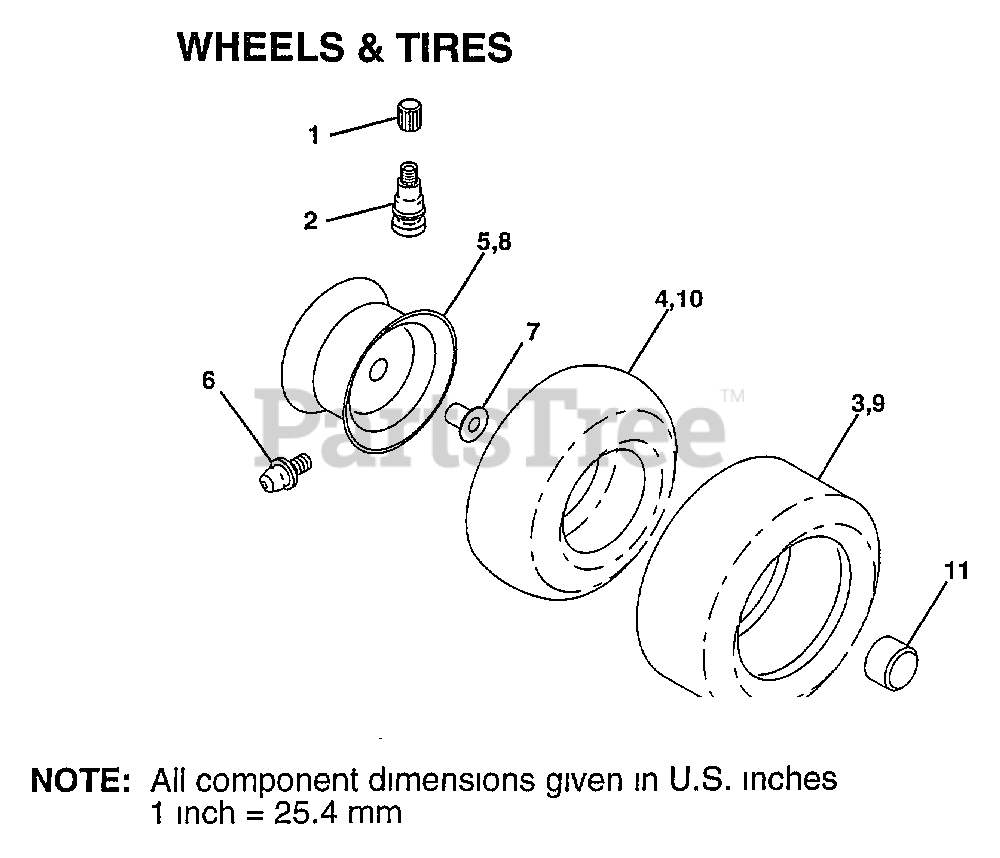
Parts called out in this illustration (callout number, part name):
1	VALVE CAP
2	VALVE STEM LT
4	TUBE.16X6.5/7.5-8
5	RIM.FRONT.
6	ZERK FITTING M
6	FITTING LT
7	"FLANGE, BEARING"
8	"WHEEL,REAR"
10	TUBE.23X8/10-12
11	HUB CAP
